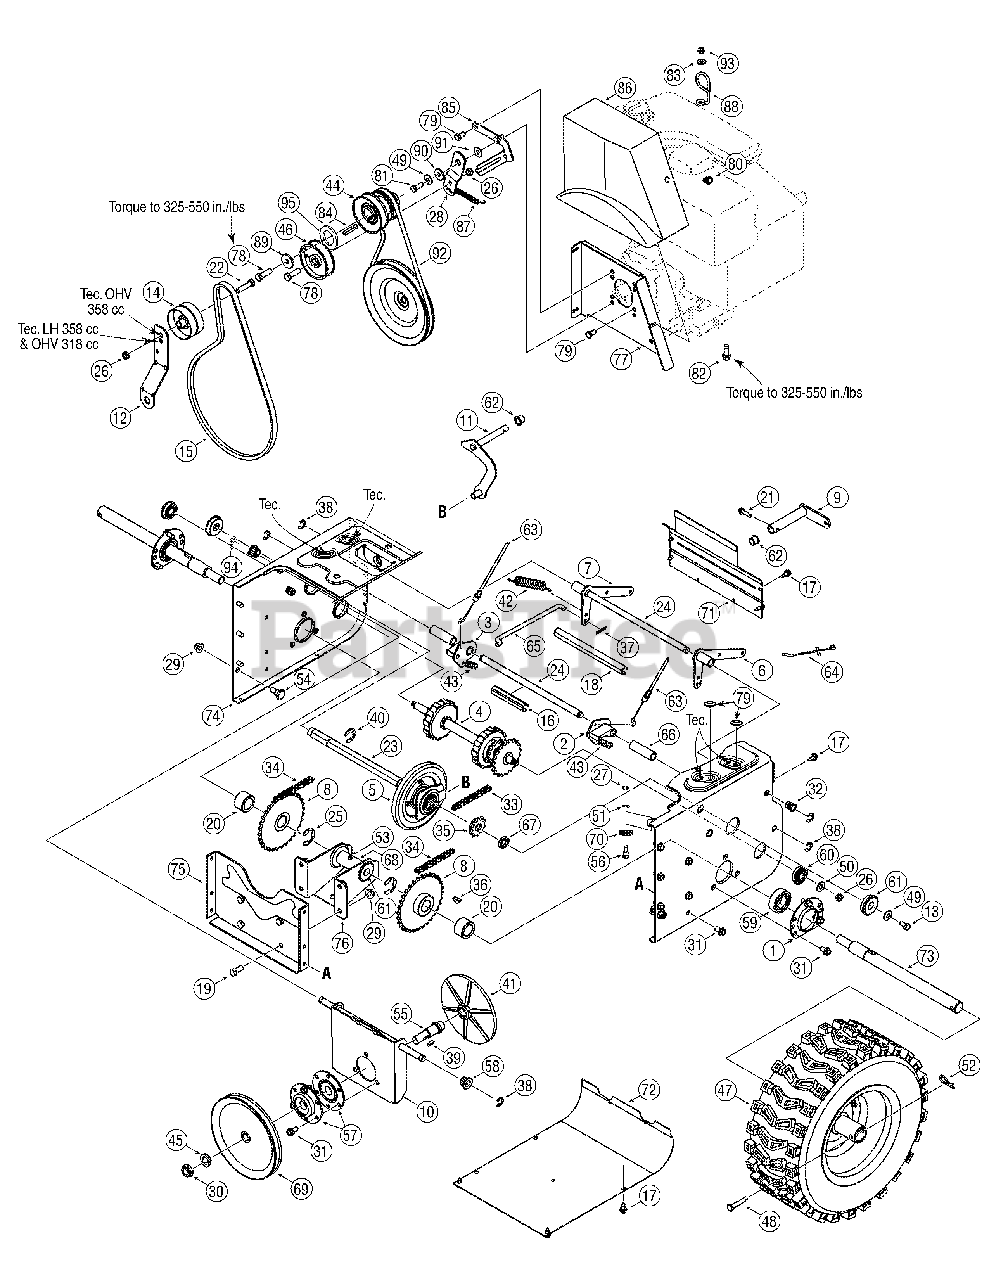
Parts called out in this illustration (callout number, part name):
1	Bearing Housing
2	LH Dog Assembly
3	RH Dog Assembly
4	Steering ShaftAssembly
5	Wheel Ass’y Bearing 6.0" OD
6	ActuatorAuger BracketAss’y
7	Actuator Drive Bracket Ass’y
8	32T Sprocket Ass’y
9	Shift Arm Ass’y
10	Friction Drive Support
11	Shift Ass’y Rod
12	Auger Idler Bracket
13	Hex L-Bolt 5/16-18 x .62
14	Flat Idler Pulley
15	V-Belt 1/2 x 44" Lg. (358 cc OHV)
15	V-Belt 1/2 x 42" Lg.
16	Spacer .51 ID x 3.66" Lg.
17	Hex Wash Hd TT Scr. 1/4-20 x .625
18	Spacer .51 ID x 7.895" Lg.
19	Hex Hd. C-Sunk Scr. 3/8-16 x .880 Gr. 5
20	Spacer 1.0 ID x 1.5" Lg.
21	Hex Bolt 1/4-20 x 1.00
22	Hex Scr 3/8-24 x 1.50 Gr. 5
23	Hex Drive Shaft
24	ActuatorShaft
25	Retaining Ring
26	Hex Nut 3/8-24
27	Hex Nut 1/4-28
28	Drive Idler Bracket
29	Flange L-Nut 3/8-16 Gr. F Nylon
30	Hex Jam Locknut 5/8-18 Gr. 5 Nylon
31	TT Screw, 5/16-18 x .75
32	Nut Insert 3/8-16 UNC
33	#41 Chain 1/2" pitch x 36 links- Endless
34	#420 Chain 1/2" pitch x 40 links-Endless
35	10T Sprocket #41 x .500
36	Woodruff Key
37	Int. Cotter Pin 5/16 DIA
38	E-ring
39	No. 61 Hi-Pro Key 3/16 x 5/8
40	Retaining Ring E-Type .875 dia.
41	Aluminum DrivePlate
42	IdlerExtension Spring
43	Extension Spring .47 OD x 2.03 Lg.
44	Pulley, Dbl 3.25 OD
45	Lockwasher 5/16 ID
46	Flat Idler Pulley 3.0 OD
47	Tire Only
47	Bearing
47	Valve
48	Clevis Pin
49	Cupped Washer .345 ID x .88 OD x .06
50	Flat Washer .385 ID x .87 OD x .06
51	L-Wash 1/4 ID
52	Int. Cotter Pin
53	Grease
54	Shld. Scr. .500 Dia. x .335" Lg.
55	Drive Plate Spindle
56	Hex Shld.Scr.1/4-28 x .375
57	Bearing Hsg. Ass’y.
58	Hex Flange Bearing
59	Self aligning brg. 1.0 ID
60	Ball Bearing .5625 ID x 1.3750 x .437
61	Ball Bearing w/snap ring
62	Flange Bushing .500 ID x .627 OD
63	Steering Cable
64	Auger Idler Cable
65	Drive Clutch Rod
66	Split Spacer 1/2 x 5/8 x 2.69
67	Spacer .625 ID x 1.0 OD x .23
68	Spacer .6725ID x 1.125OD x 2.485
69	1/2" "V" Pulley .625 ID x 7.50 OD
70	Cable Guide Roller
73	Axle.995 x 14.10" Lg (30" & 33")
73	Axle .995 x 20.4" Lg. (45")
76	Axle Brg. Support Bracket
77	Belt Cover Bracket
78	Hex Screw 3/8-24 x 1.25 Gr. 8 Special
79	Hex Screw 5/16-24 x .625 Gr. 5
80	Hex Wash HD S-Tapp Scr 5/16-18 x .50
81	Hex HD. Cap Scr. 5/16-24 x 0.875 Lg. Gr 8
81	Hex HD. Cap Scr. 5/16-24 x 1.25 Lg. Gr 5
82	Hex Wash HD Tap Scr 3/8-16 x 1.00
83	Flat Washer .28 ID x .74 OD x .063
84	Square Key 1/4 x 1/4 x 1.50" Lg.
85	Belt Keeper Bracket
86	Belt Cover
87	Brake Return Ext. Spring 3.18" Lg.
88	Cable ControlWire
89	Flat Washer .406 ID x 1.25 OD x .160
90	Shoulder Spacer .25 THK
91	Flat Washer .349 x .879 x .063 (358 cc OHV)
91	Spacer .33 ID x 1.01 OD x .36
92	V-Belt 3/8 x 35.5" Lg. (358 cc OHV)
92	V-Belt 3/8 x 34.4" Lg.
93	Hex Flg. L-Nut 1/4-20 Gr. F Nylon
94	Speed Nut .50
95	Spacer 1.02 x 1.63 x .1425
96	Plug 3/8"
